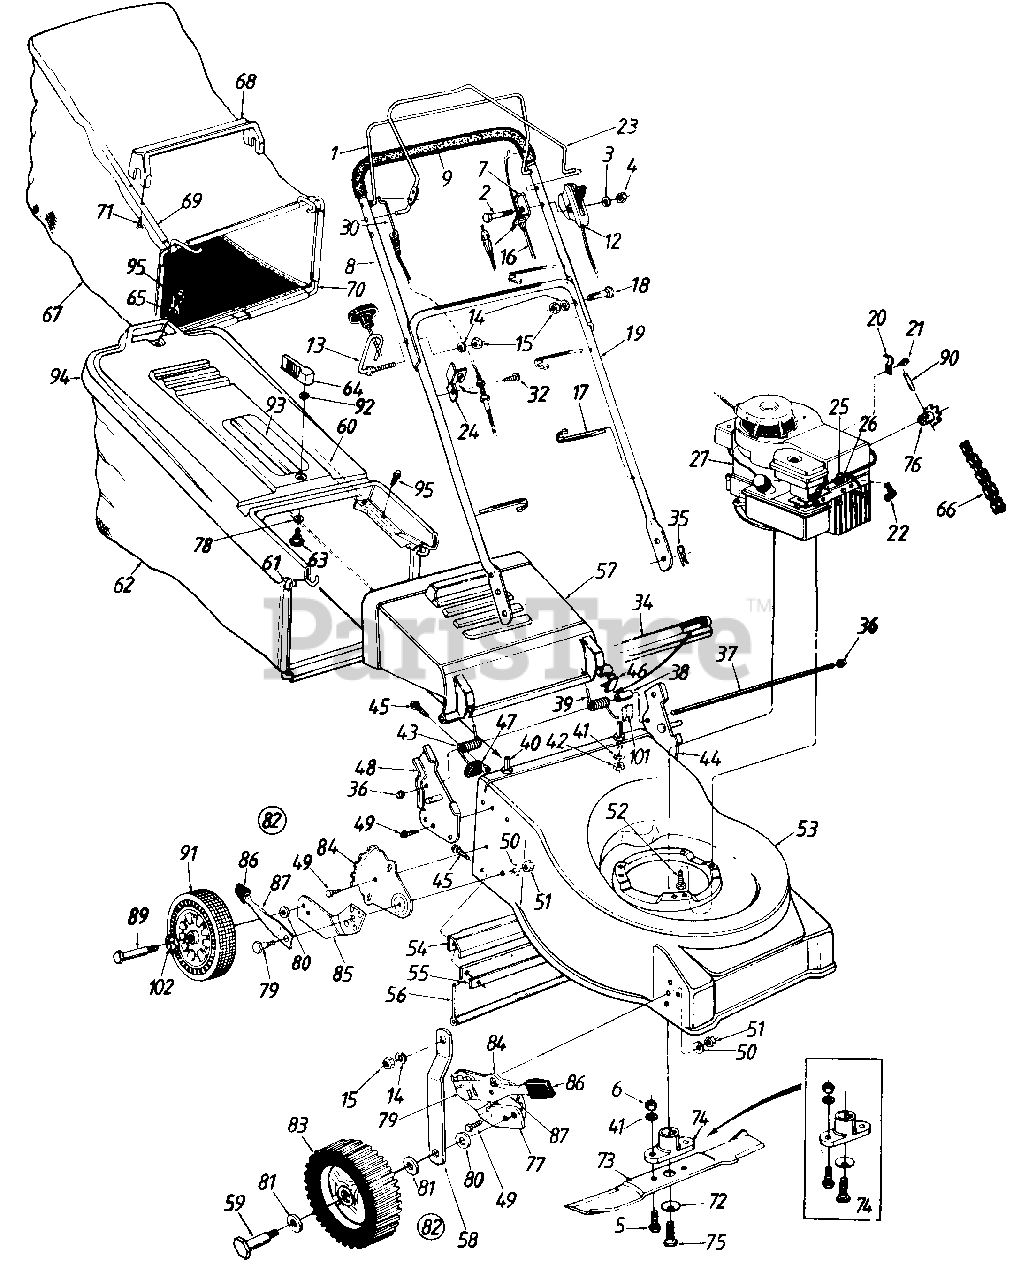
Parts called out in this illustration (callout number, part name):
1	Control Handle
2	Hex Bolt 1/4-20 x 1.75" Lg.
3	Spr. Wash. .265" I.D. x .562" O.D.
4	Hex Nut 1/4-20 Thd.
5	Hex Bolt 3/8-24 x 1" Lg.
6	Hex Nut 3/8-24 Thd.
7	Cable Brkt.
12	Throttle Control Ass'y. Comp.- 56.62" Lg.
13	Rope Guide Bolt
14	L-Wash. 5/16" I.D.
15	Hex Nut 5/16-18 Thd.
16	Control Cable-43" Lg.
17	Cable Tie
18	Curved Carriage Bolt 5/16-18 x 1.38" Lg.
19	Lower Handle
20	Cable Clamp
21	Hex B-Tap Scr. #10 x .38" Lg.
22	Spark Plug Boot
23	S.P. Bail
24	Cable Mounting Brkt.
25	Cable Clamp
26	Hex AB-Tap Scr. #8 x .5" Lg.
27	Engine
30	Drive Cable-47" Lg.
32	Hex Wash. AB-Tap Scr. 5/16" x.75" Lg.
34	Seal-Extrusion
35	Int. Cotter Pin 5/16" Dia.
36	Cap Speed Nut
37	Hinge Pin 17.75" Lg.
38	Spacer.255" I.D.
39	Torsion Spring-L.H.
40	Shld. Pin 3/8-24 x 1.43" Lg.
41	L-Wash. 3/8" I.D.
42	Hex Jam Nut 3/8-24 Thd.
43	Torsion Spring-R.H.
44	Handle Brkt. Ass'y.-L.H.
45	Torx Mach. AB-Tap Scr. 1/4 x .62" Lg.
46	Deflector Plug
47	Corner Plug
48	Handle Brkt. Ass'y.-R.H.
49	Hex L-Wash. AB-Tap Scr. 1/4 x .62" Lg.
50	Bell-Wash. .39" I.D. x 1.38" O.D.
51	Hex Nut 3/8-16 Thd.
52	Hex TT-Tap Scr. 3/8-16 x 1"
57	Rear Chute Deflector
58	Link 5.06" Lg.
59	Front Axle Bolt
62	Grass Bag
63	Shld. Bolt .342" Dia. x .268"
64	Grass Catcher Locking Knob
65	Fl-Wash. .281" I D
66	#48 Chain 1/2" Pitch 50 Links
67	Grass Bag
68	Bag Handle
70	Front Catcher Frame
71	Hex AB-Tap Scr. #12 x 1.25"
72	Bell-Wash. .39" I.D. x 1.12" O.D.
73	21" Blade
74	Blade Adapter Kit
75	Hex Bolt 3/8-24 x 1.5" Lg.
76	10 Tooth Sprocket Ass'y.
77	Pivot Bar-R.F. & L.R.
78	Bowed Washer
79	Shld. Bolt .50" Dia. x .357"
80	Bell-Wash. .38" I.D. x .88" O.D.
81	Fl-Wash. .531 " I.D.
82	Front Height Adj. Ass'y. Comp.-L.F. & R.R.
83	Front Wheel Ass'y. Comp.
84	Index Plate
85	Pivot Bar-L.F. & R.R.
86	Spring Lever Knob
87	Spring Lever
89	Rear Axle Bolt
90	Spring Pin 3/16" Dia.
91	Rear Wheel Ass'y. Comp.
92	Internal L-Wash. 1/4" I.D.
93	Hardtop Handle
94	Hardtop Bag Cover
95	Hex AB-Tap Scr. 1/4 x .62" Lg.
102	Wave Wash. .53" I.D. x .78" O.D.
